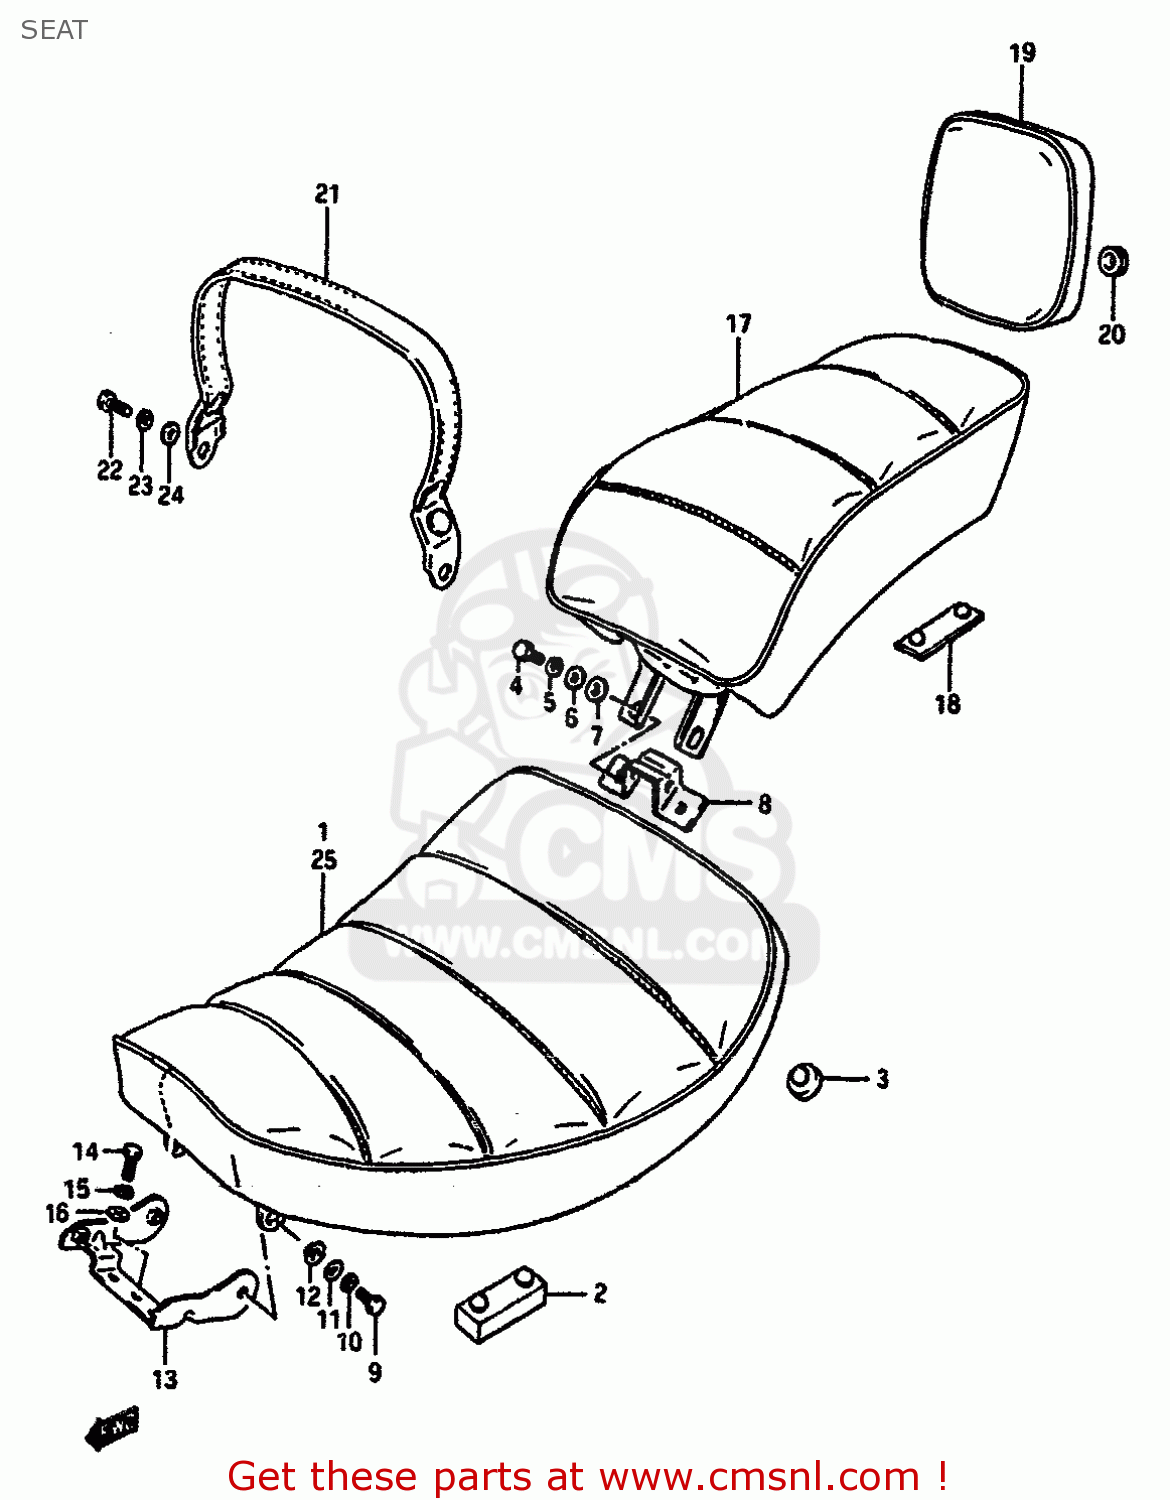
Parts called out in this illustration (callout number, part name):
1	SEAT ASSEMBLY
2	CUSHION,SEAT
3	CUSHION
4	BOLT
5	WASHER,LOCK
6	WASHER, LOWER
7	WASHER
8	PLATE,FR SEAT HOOK & RR
9	BOLT
10	WASHER,LOCK
11	WASHER, LOWER
12	WASHER
13	BRACKET,SEAT,FRONT
14	BOLT
15	WASHER,LOCK
16	WASHER
17	SEAT SET,PILLION
18	CUSHION
19	PAD ASSY,SEAT
20	CUSHION
21	BAND,SEAT
22	BOLT
23	WASHER,LOCK
24	WASHER
25	SEAT ASSEMBLY
